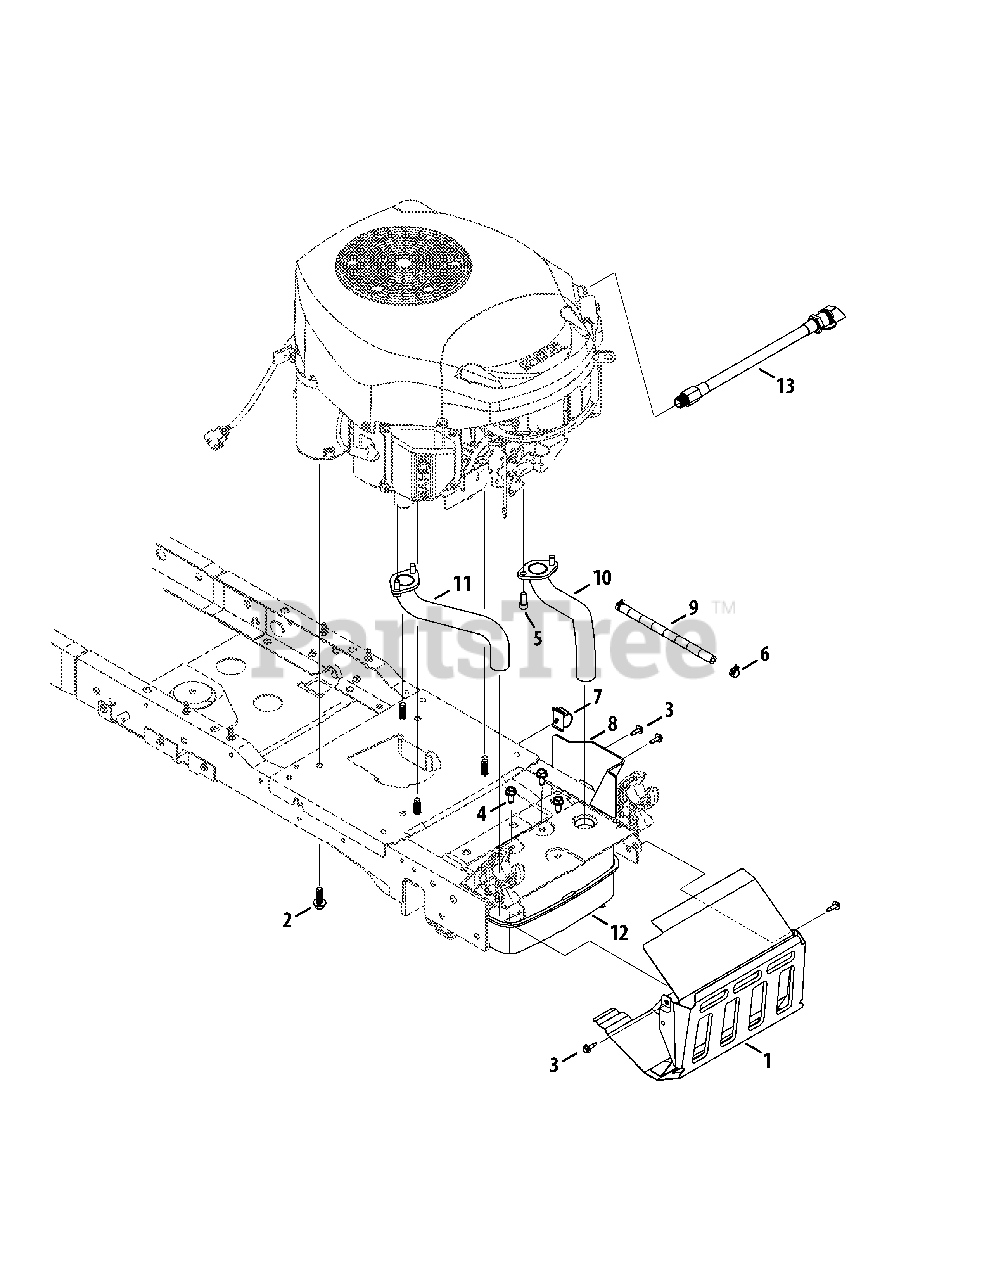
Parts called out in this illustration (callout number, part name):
1	Shield Ass’y, Muffler
2	Screw, Self-tapping, 3/8-16, 1.0
3	Screw, M6-1 x .625
4	Screw, Self-tapping, M8-1.25, .750
5	Screw, Sokt Head, 5/16-18, .750
6	Clamp, Hose, .490 Dia.
7	Push Mount Wire Clip, .750
8	Muffler Shield
9	Hose, Fuel, Low Permeation, 1/4
10	Exhaust Pipe, LH
11	Exhaust Pipe, RH
12	Muffler, Kohler
13	Drain, Oil
